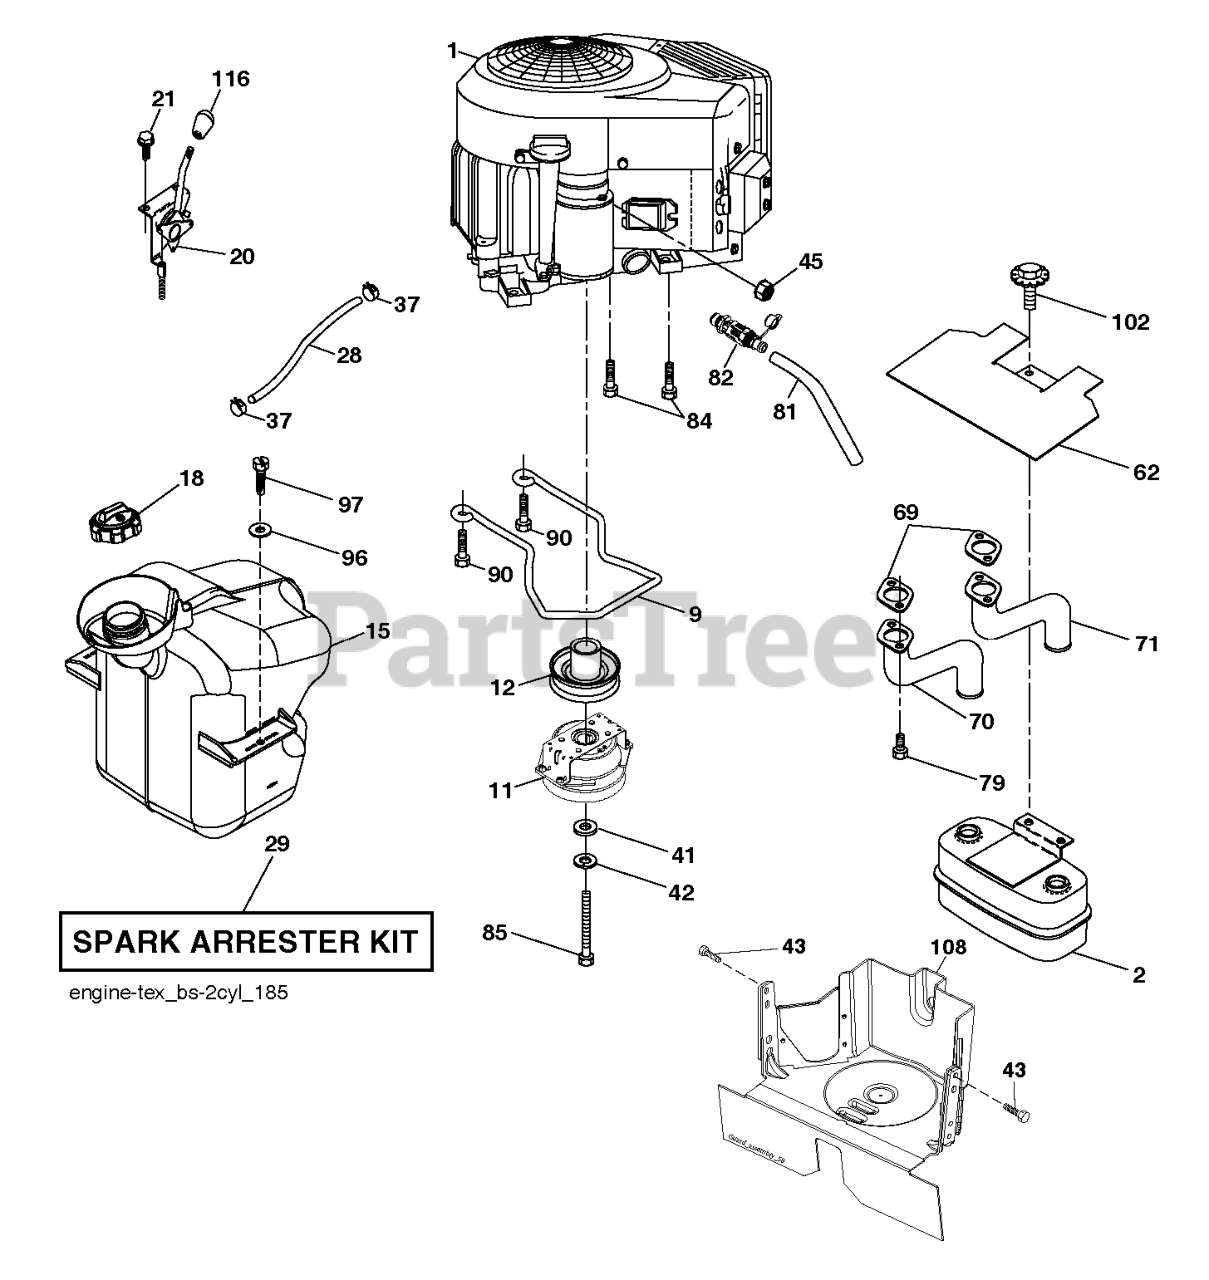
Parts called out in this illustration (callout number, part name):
2	MUFFLER.ASM.TWIN.MNTG.BRACKET
11	CLUTCH MAGNETIC CLUTCH & BRAKE
12	PULLEY.ENGINE.TUFFTORQ
15	FUEL TANK TANK. ASSEMBLY. EXTE
18	CAP ASM.FUEL.2.25"FR.
20	THROTTLE.PRO.RSTART. 38
28	LINE.FUEL.20
29	KIT.SPARK ARRESTOR 794945 B&S
37	HOSE CLAMP
62	SHIELD.HEAT.MUFFLER
69	GASKET.MUFFLER
70	EXHAUST.TUBE.LH.BS/TWIN
71	EXHAUST.TUBE.RH.B&S.TWIN.INTEK
81	TUBE, DRAIN OIL ASM.
82	VALUE.OIL.DRAIN
84	SCREW.3/8-16
85	BOLT.HEX.7/16-20X3.75.GR5.RED
90	SCREW 3/8-16X1
97	SCREW HEXWSHR 1/4-20X3/4
102	SCREW
108	COVER ENGINE PULLEY COVER WITH
116	KNOB - SHIFT
